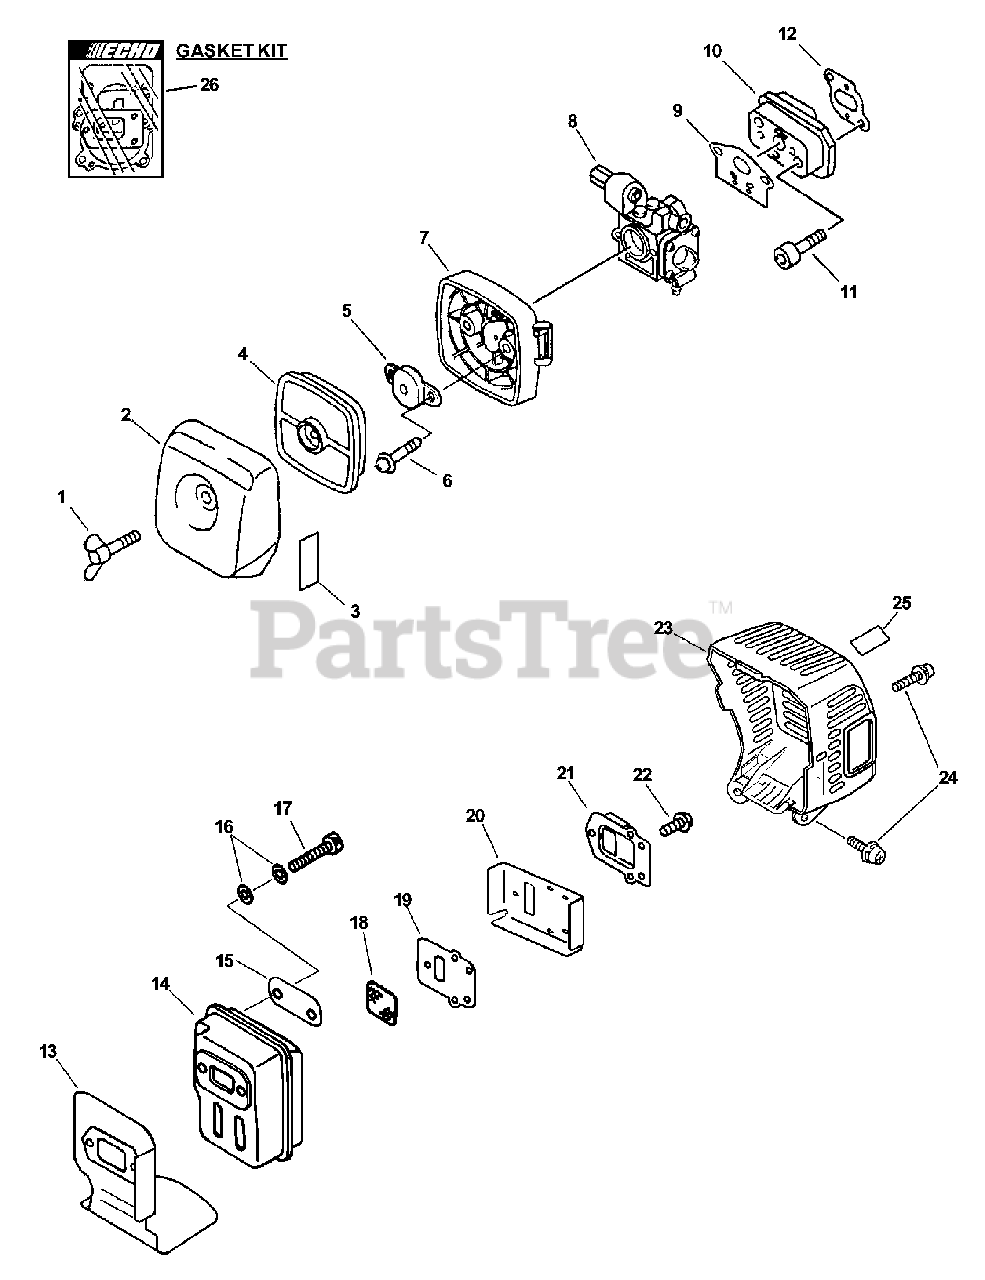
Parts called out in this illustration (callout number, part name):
1	BOLT, WING 5×20
2	COVER, AIR FILTER - GRAY
3	LABEL, CHOKE
4	FILTER, AIR - SINGLE LAYER
5	PLATE, PREVENT
6	SCREW 5×60
7	CASE, AIR FILTER - GRAY
8	CARBURETOR - RB-K57A
9	GASKET, CARBURETOR
10	INSULATOR, INTAKE
11	BOLT 5×25
12	GASKET, INTAKE
13	HEAT SHIELD, EXHAUST
14	MUFFLER
15	PLATE, EYE
16	CONICAL WASHER
17	BOLT 5×55
18	SCREEN, SPARK ARRESTER
19	GASKET, EXHAUST
20	GASKET, EXHAUST
21	GUIDE, EXHAUST
22	SCREW 4×10
23	COVER, EXHAUST
24	BOLT 5×12
25	LABEL, CAUTION - HOT
26	GASKET KIT
